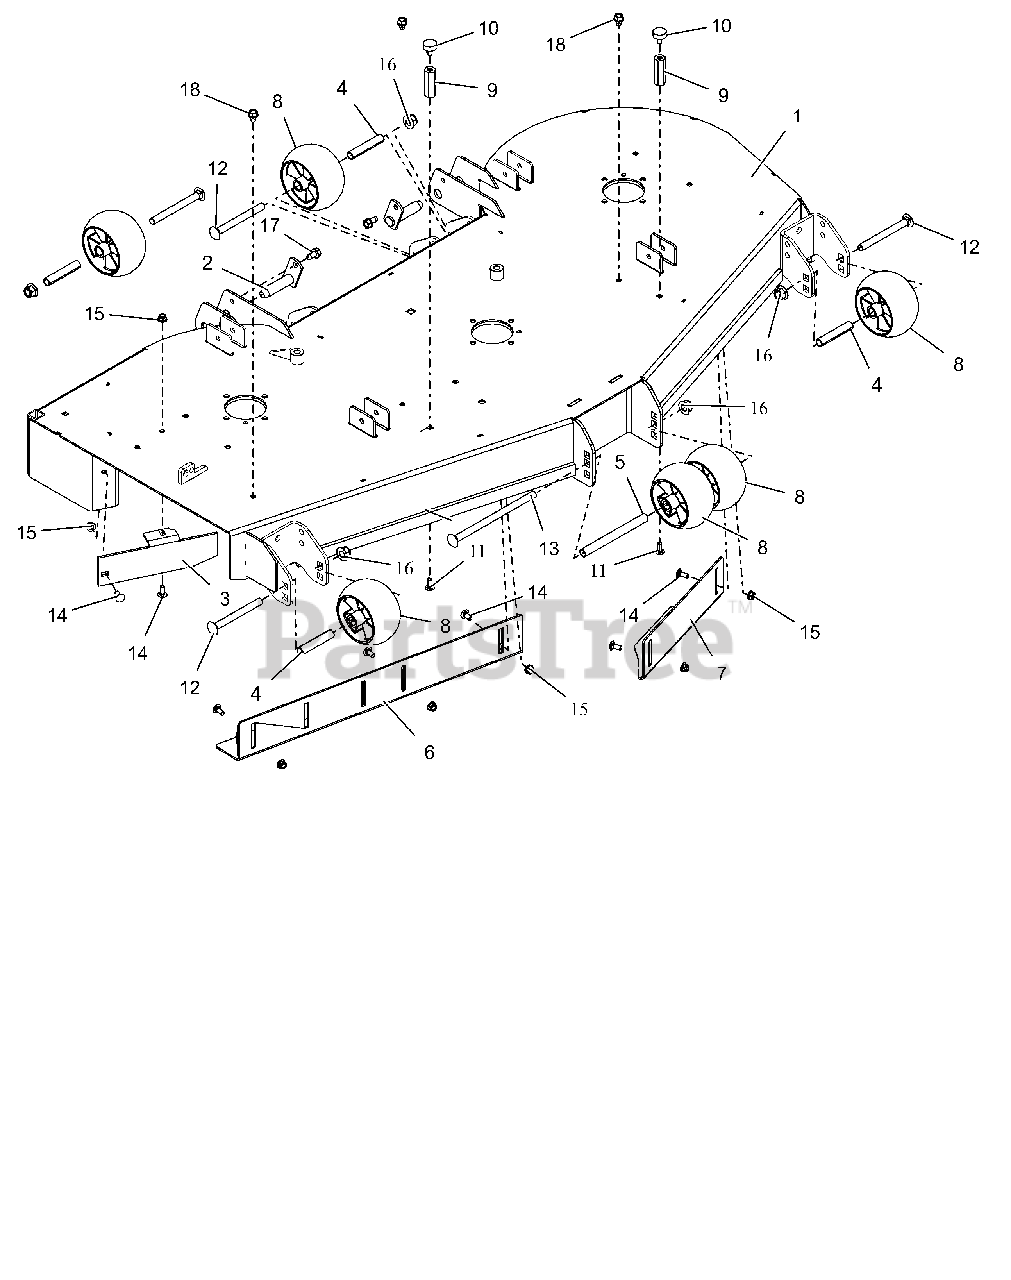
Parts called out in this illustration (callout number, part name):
1	KIT, 60" MOWER DECK W DECALS
2	WLDMT, MOWER MTG. PIN (BLACK)
3	60" DISCHARGE BAFFLE - RED
4	SPACER, .510X.625X3.35
5	SPACER, .510X.625X6.50
6	60" RH VACUUM BAFFLE - RED
7	60" LH VACUUM BAFFLE - RED
8	ANTI-SCALP WHEEL - 5X3 CTR
9	NUT, .31-18X2.25 LG COUPLING
10	BUMPER, RUBBER
11	BLT,RDHDSQNK .31-18X.75 LOCTIT
12	BLT-RDHDSQNK .50-13X5.00 GR5YZ
13	@BLT-RDHDSQNK .50-13X8.50 G5YZ
14	@BLT-RDHDSQNK .31-18X.75 G5YZ
15	@NUT-LK-NYL-FLG .31-18 YWZC
16	@NUT-LK-NYL-FLG .50-13 YWZC
17	@SCR-TAP .38-16X.75 HWH TR YWZ
18	@SCR-TAP .38-16X.50 HWH TR YWZ
